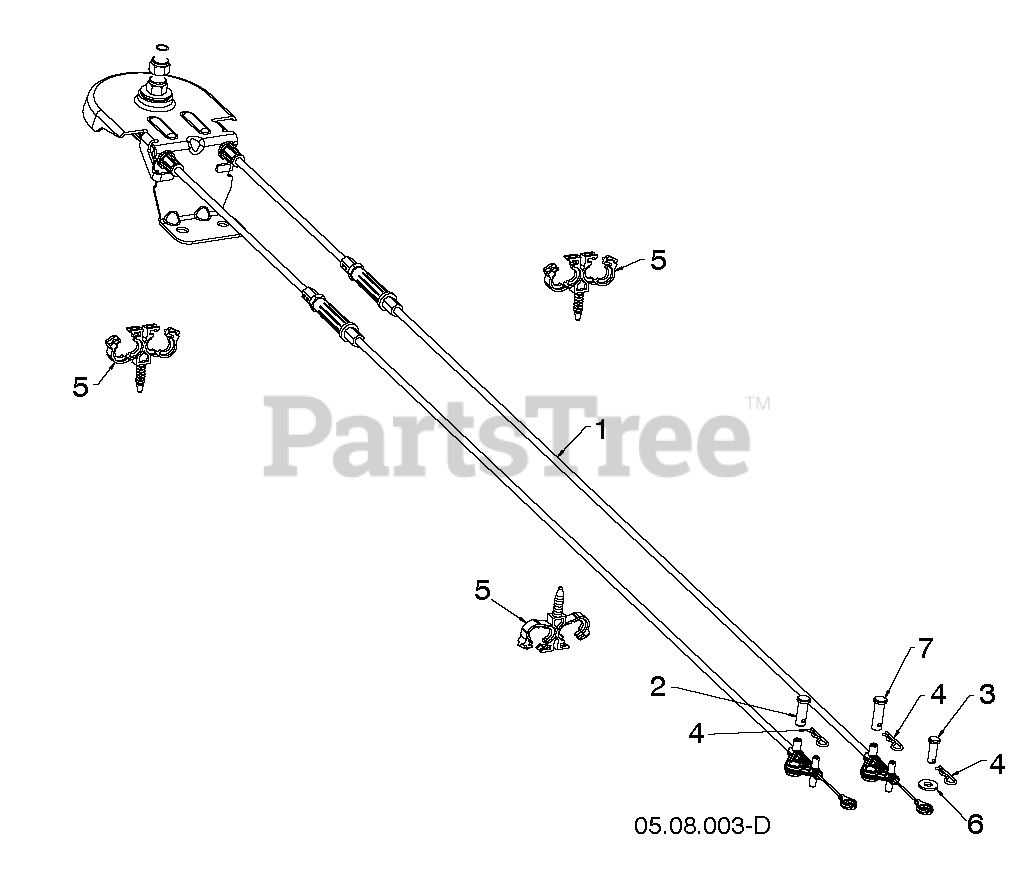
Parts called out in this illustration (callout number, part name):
1	CABLE.ROTATOR.ASSEM.SNOW
2	PIN CLEVIS 5/16X.875
3	PIN.CLEVIS
4	HAIRPIN.SOFT.ZINC.059X1.125
5	CLIP.CONDUIT.DOUBLE LOOP
6	WASHER FLAT_.250 X .625 X .06
7	PIN CLEVIS 5/16 X 1.0 L
